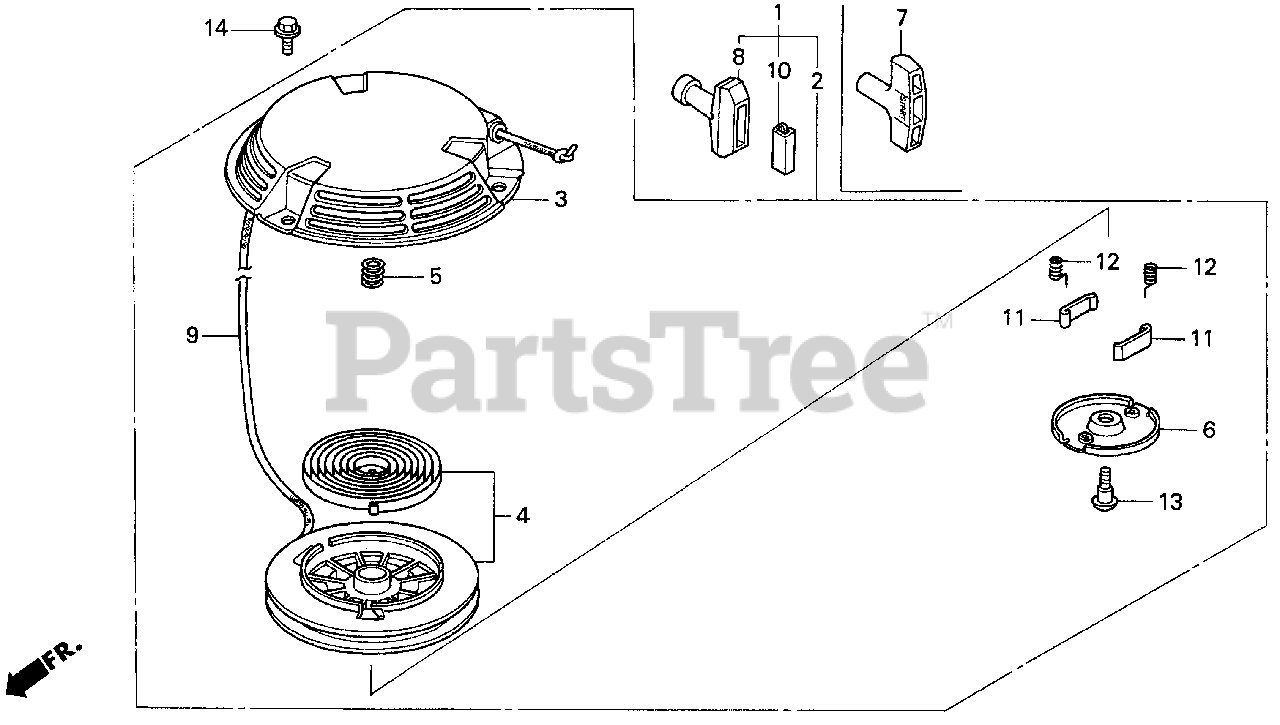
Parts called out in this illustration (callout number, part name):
2	STARTER ASSY., RECOIL
3	HOUSING ASSY.
4	PULLEY & SPRING ASSY.
5	SPRING, BRAKE
6	RETAINER
7	KNOB, RECOIL STARTER
9	ROPE (#4X91")
11	DOG
12	SPRING, DOG
13	SCREW, CENTER
14	BOLT, FLANGE (6X8)
